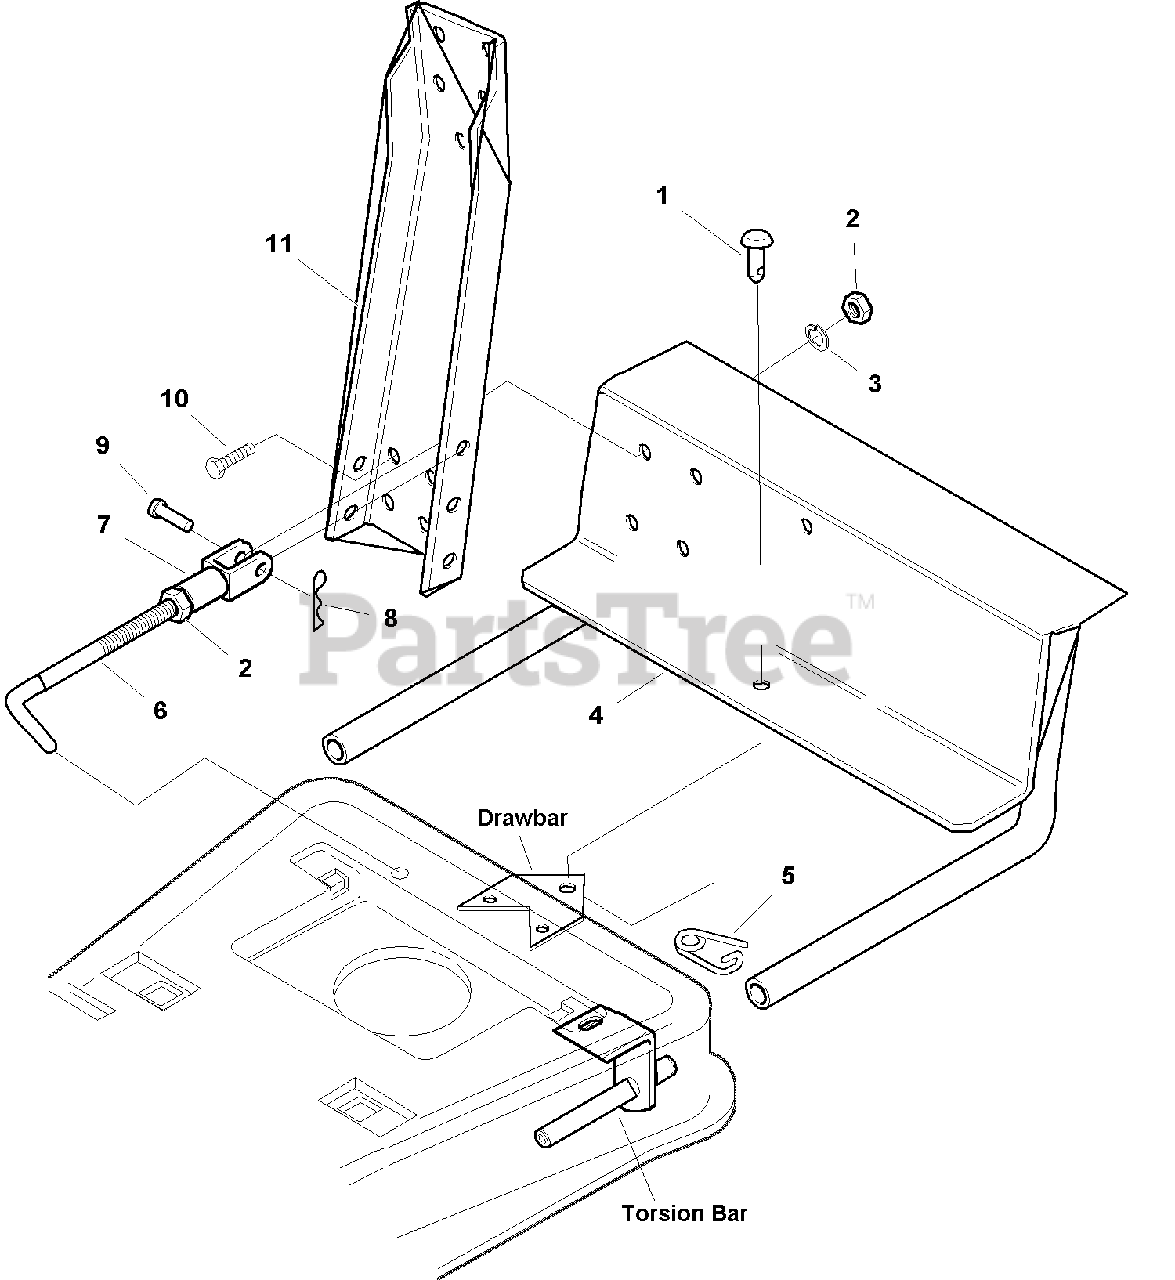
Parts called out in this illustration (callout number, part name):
1	PIN, Round Head, Drilled
2	NUT, Hex, 3/8-16
3	LOCKWASHER, 3/8
5	CLIP, Safety Pin
7	CLEVIS, 3/8-16
8	CLIP, Hair Pin
9	PIN, Yoke, Drilled
10	CAPSCREW, Hex Head, 3/8-16 x 1
11	SUPPORT, Upright
